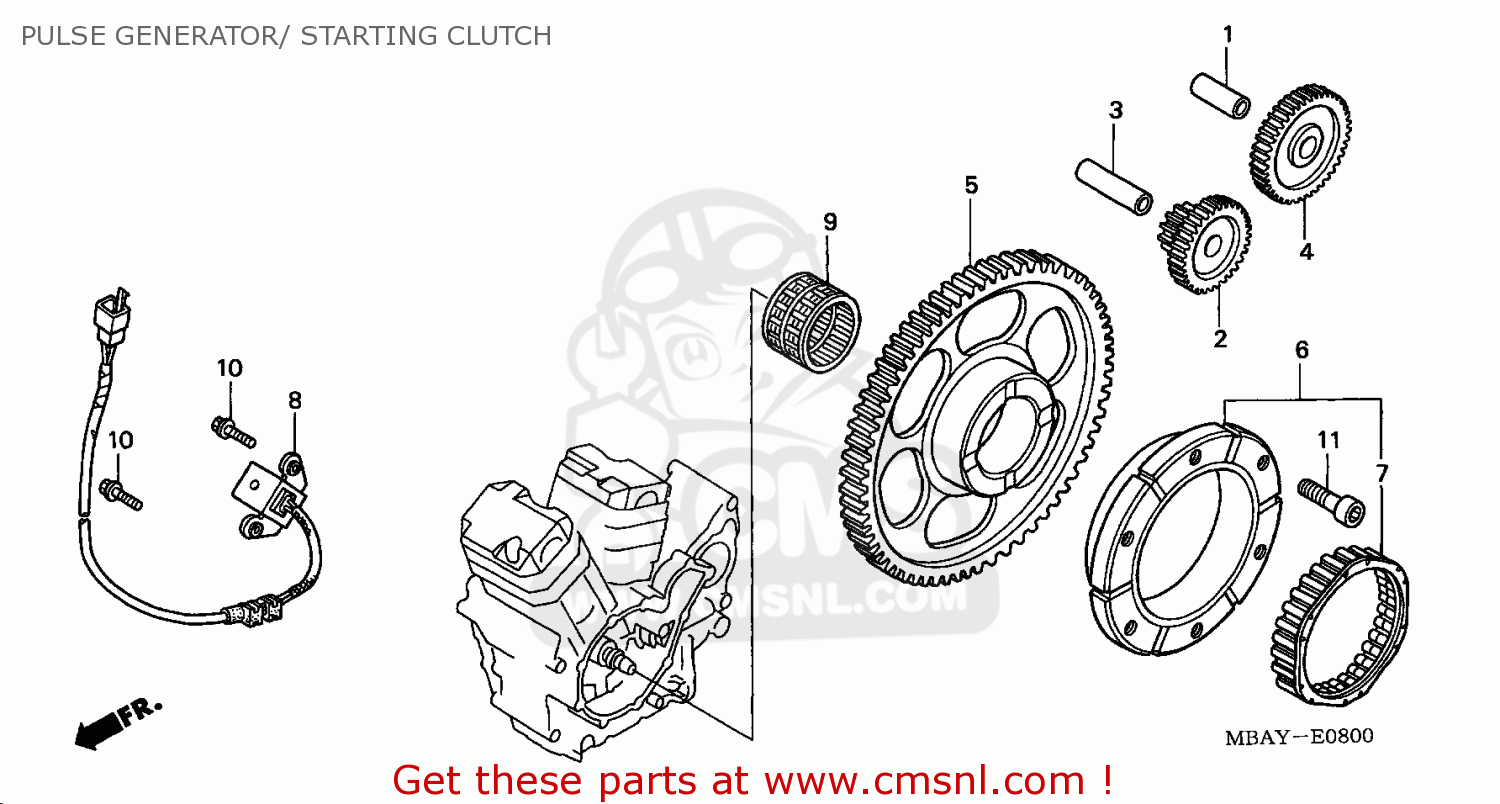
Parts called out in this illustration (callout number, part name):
2	GEAR RED START
3	PIN 10X44
4	GEAR,STARTER
5	GEAR COMP,STARTIN
6	OUTER ASSY,STARTI
7	CLUTCH,ONEWAY
8	PULSE GEN ASSY
9	BRG,NEEDLE 32X40X
11	BOLT,SOCKET,8X35
